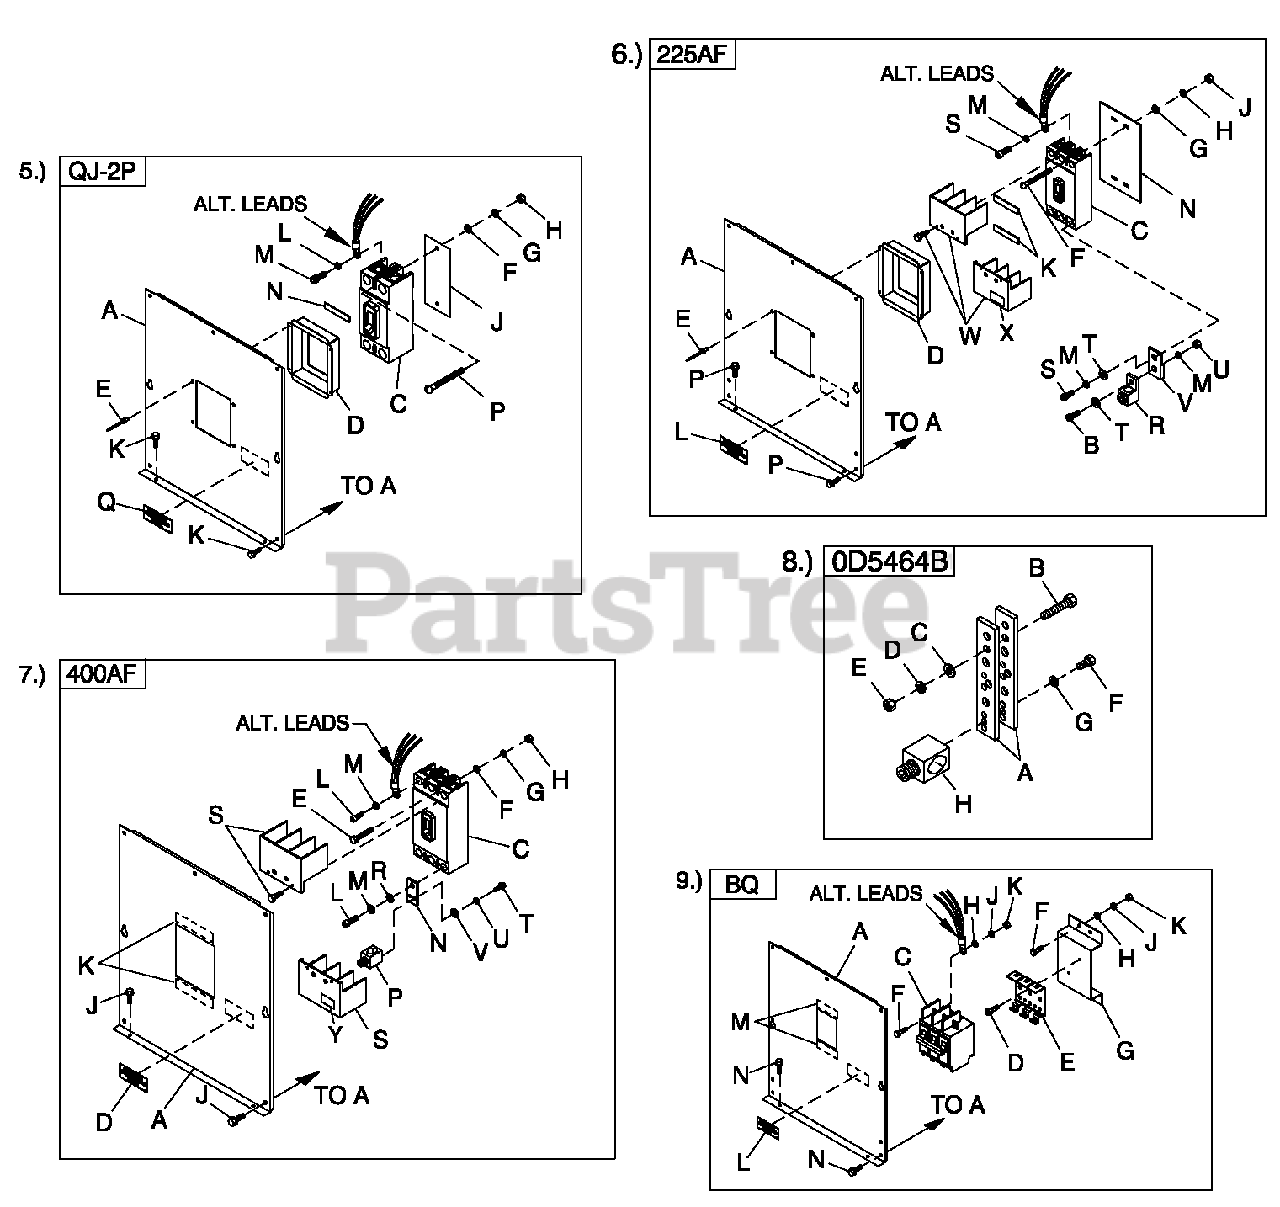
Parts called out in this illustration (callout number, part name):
9	UL CIRCUIT BREAKER (BQ)
A	COVER QJ 2P FRMCB
C	CB 0225A 240V 2P S QJ22
D	COVER QJ 2P CB DISH
E	RIVET POP .125 X .275 SS
F	WASHER FLAT 1/4-M6 ZINC
G	WASHER LOCK M6-1/4
H	NUT HEX 1/4-20 STEEL
J	INSULCB2PQJ
K	SCREW THF M6-1 X 16 N WAZ/JS
L	WASHER LOCK 3/8
M	SCREW SHC 3/8-16 X 3/4 G8.8 NZ
N	TAPE ELEC 1/2 FOAM (AS REQ'D)
P	SCREW RHM 1/4-20X3
Q	DECAL CUSTOMER CONNECT INSIDE
A	COVER CB C2-C4 (225AF)
B	SCREW SHC M8-1.25 X 25 G12.9
C	CIRCUIT BREAKERS 200A FRAME (3P)
D	COVER CB DISH 225AF (3P)
F	SCREW RHM #8-32X3-1/4
G	WASHER FLAT #8 ZINC
H	WASHER LOCK #8-M4
J	NUT HEX #8-32 STEEL
K	TAPE ELEC 1/2 FOAM
L	DECAL CUSTOMER CONNECT INSIDE
M	WASHER LOCK M8-5/16
N	INSULATOR CB225AF(3P)
P	SCREW THF M6-1 X 16 N WAZ/JS
R	LUG SLDLSS 300 MCM-6 AL/CU
S	SCREW SHC M8-1.25X 20G8
T	WASHERFLAT 5/16-M8ZINC
U	NUT HEX M8-1.25 G8 CLEAR ZINC
V	BUS BAR 200A LUG ADAPTOR
W	TERMINAL COVER CB
X	DECALTERMINALSHOCK HZD BI
A	COVER CB C2-C4 400AF
C	CIRCUIT BREAKERS 400A FRAME
D	DECAL CUSTOMER CONNECT INSIDE
E	SCREW RHM 1 0-3 2X4
F	WASHER FLAT #10 ZINC
G	WASHER LOCK #10
H	NUT HEX #10-32 STEEL
J	SCREW THF M6-1 X 16 N WAZ/JS
L	SCREW SHC M10-1.5X25G12.9
M	WASHER LOCK M10
N	BUS BAR CB ADAPTER 225-400 A
P	LUG SLDLSS 600/250-1/0 X 1/4-28
S	TERM COVER CB
T	SCREW HHC 1/4-28 X 1/2 G5
U	WASHER LOCK M6-1/4
V	WASHERFLAT 1/4-M6 ZINC
W	SCREW SHC M10-1.5X25G12.9
X	WASHER LOCK M10
Y	DECAL TERMINALSHOCK HZD BI
A	BUS BAR NEUTRAL BLOCK 390
B	SCREW HHC M8-1.25 X 45 G8.8 FT
C	WASHER FLAT 5/16-M8 ZINC
D	WASHER LOCK M8-5/16
E	NUT HEX M8-1.25G8YEL CHR
F	SCREW HHC 1/4-28 X 3/4 G5
G	WASHER LOCK 1/4-M6SS
H	LUG SLDLSS 600/250-1/0 X 1/4-28
A	COVER BQ CIR BREAKER CPL 3P
C	CB0125A2P 240V SBQ2 LL
D	SCREW PHTTM4-0.7X 10 ZYC
E	BRKT CB MTG BACK
F	SCREW RHM #10 -3 2X3 /4
G	BRKT BQCB STANDOFF
H	WASHER FLAT #10 ZINC
J	WASHER LOCK #10
K	NUT HEX #10-32 STEEL
M	TAPE ELEC 1/2 FOAM
N	SCREW THF M6-1 X 16 N WA Z/JS
